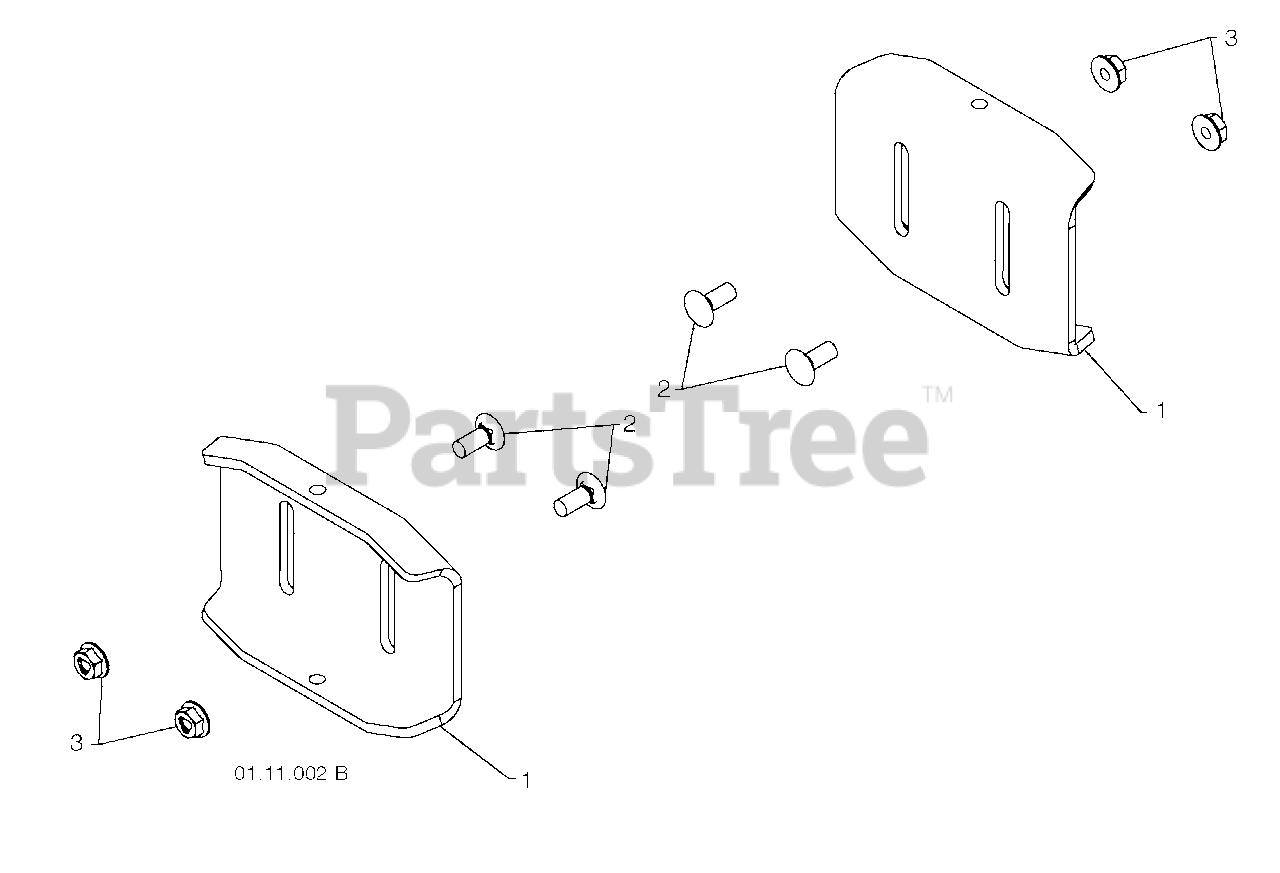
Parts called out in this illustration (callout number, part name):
1	SKID PLATE
2	CARRIAGE BOLT 5/16-18 X .750
3	NUT 5/16-18
